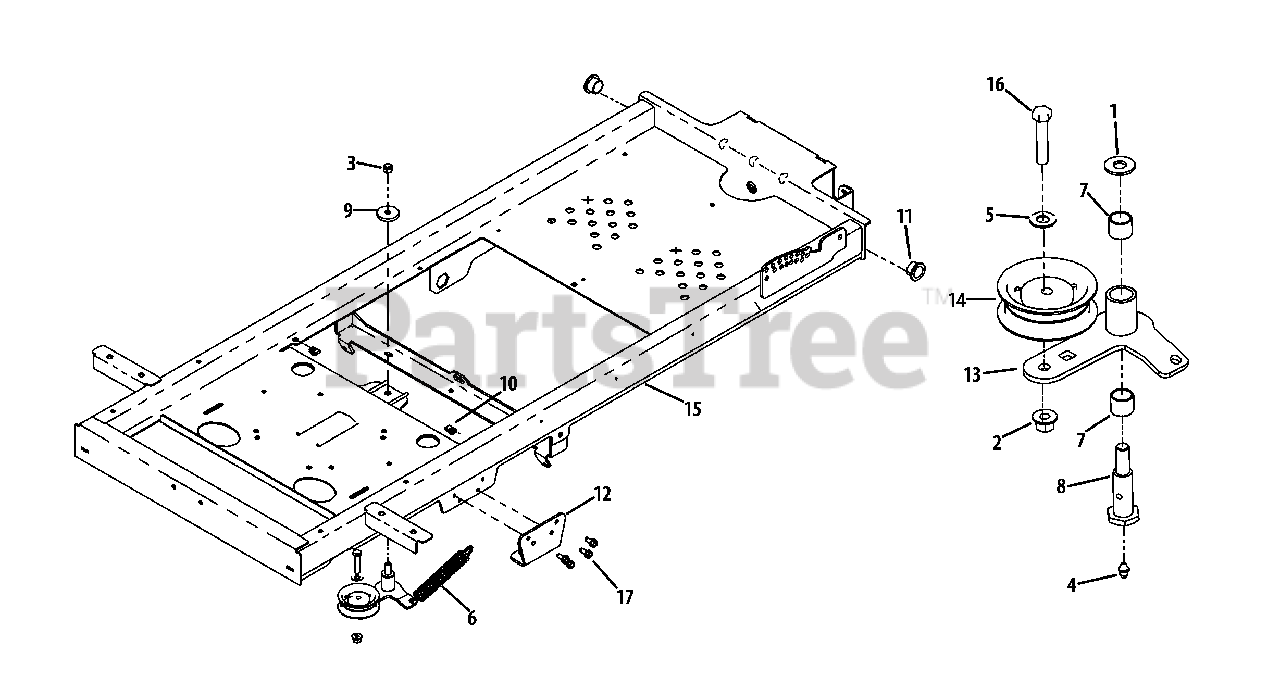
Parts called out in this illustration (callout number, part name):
1	Flat Washer, .469 x .875 x .105
2	Counterlock Flange Nut, 3/8-16
3	Nylock Nut, 7/16-14
4	Straight Grease Fitting, 1/4-28
5	Flat Washer, .406 x .875 x .059
6	Extension Spring, 1.00 x 5.00
7	Bearing Sleeve
8	Shoulder Bolt
9	Flat Washer, .45 x 1.5 x .172
10	Speed Nut, U-Type 1/4-20
11	Bushing, 1.00 x 1.50 x .750
12	Transmission Mounting Bracket
13	Idler Arm
14	Flat Idler Pully
15	Frame Assembly
16	Hex Cap Screw, 3/8-16 x 1-3/4
17	Self Tapping Screw, 5/16-18 x .750
